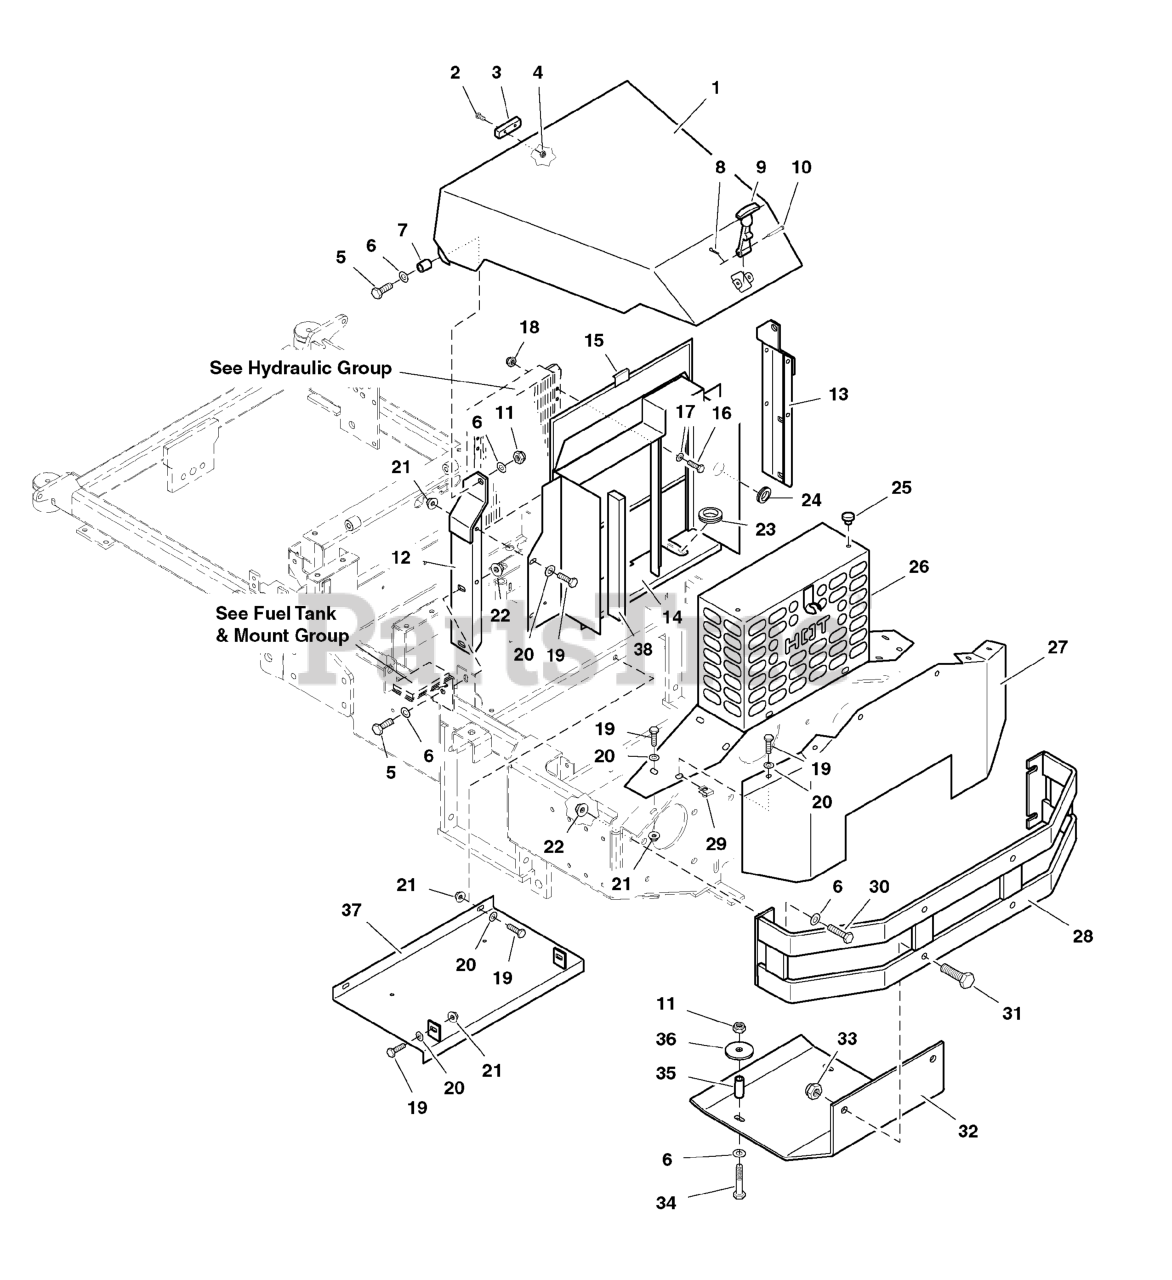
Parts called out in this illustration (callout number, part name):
1	ENGINE HOOD
2	SCREW, #8-32 x 5/8
3	RUBBER PAD
4	NUT, #8-32 Hex Nylon Lock
5	BOLT, 3/8-16 X 1" GD5 CZ
6	WASHER, 3/8 SAE
7	SPACER, .38 x .50 x .27
8	COTTER PIN
9	RUBBER LATCH
10	PIN, Clevis
11	NUT, 3/8-16 HEX NYLON LOCK
12	HOOD MOUNT-LH
13	HOOD MOUNT-RH
14	RADIATOR SHROUD
15	RADIATOR SCREEN
16	BOLT, 1/4-20 x 3/4
17	WASHER, 1/4 SAE
18	NUT, 1/4-20 HEX NYLON LOCK
19	BOLT, 5/16-18 X 1 GD5 YZ
20	WASHER, 5/16" SAE
21	NUT, 5/16-18 HEX SERRATED FLANGE (SMALL)
22	NUT, 3/8-16 Hex Serrated Flange
23	GROMMET, 1-1/4"
24	GROMMET, 7/8"
25	RUBBER BUMPER
26	MUFFLER GUARD
27	REAR SHIELD
29	BODY CLIP, 5/16-18-7GA MATERIAL
30	BOLT, 3/8-16 X 1-1/4" GD5 CZ
31	BOLT, 1/2-20 X 1-1/2, GD5 CZ
32	SKID SHIELD
33	NUT, Hex, Nylon Lock, 1/2-20
34	BOLT, 3/8-16 X 2-1/2" GD5 CZ
35	SPACER, .38 x .50 x 1.56
36	WASHER, 3/8 x 1-3/4
37	DEBRIS SHIELD
38	FOAM SEAL, 14"
